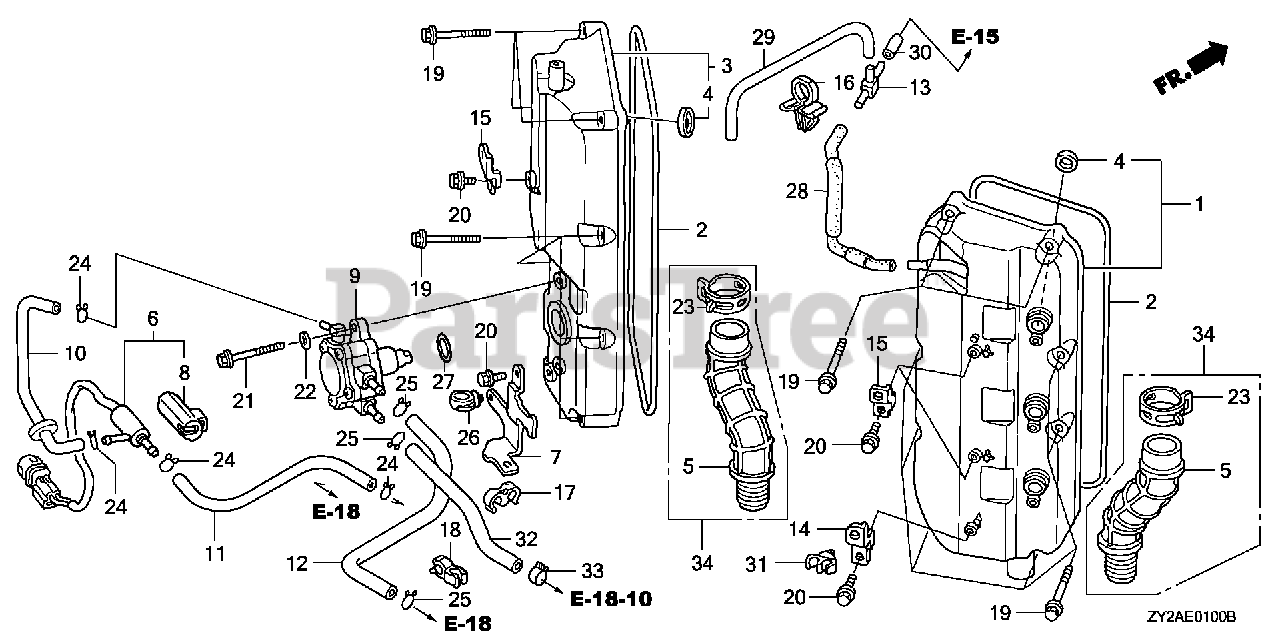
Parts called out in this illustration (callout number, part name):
1	COVER, R. CYLINDER HEAD *NH8* (DARK GRAY)
2	GASKET, HEAD COVER
3	COVER, L. CYLINDER HEAD *NH8* (DARK GRAY)
4	SEAL, SPARK PLUG TUBE (NOK)
5	TUBE, OIL
6	VALVE ASSY., SOLENOID
7	BRACKET, SOLENOID VALVE
8	GROMMET, SOLENOID VALVE
9	PUMP ASSY., FUEL (MSDS)
10	TUBE D, FUEL
11	TUBE E, FUEL
12	TUBE F, FUEL
14	BRACKET, CLIP B
15	BRACKET C, HARNESS CLIP
16	CLIP A, WIRE
17	CLIP, SENSOR HOSE
18	CLIP, SHIFT WIRE
19	BOLT, FLANGE (6X35)
20	BOLT, FLANGE (6X14) (CT200)
21	BOLT, FLANGE (8X32)
22	WASHER, PLAIN (8MM)
23	CLAMP, TUBE (D32.5)
24	CLIP, TUBE (B10)
25	CLIP, TUBE (B12)
26	CLIP, HARNESS
27	O-RING (37X2.4) (ARAI)
28	TUBE A, BREATHER
29	TUBE B, BREATHER
30	TUBE C, BREATHER
31	CLIP D, WASHER TUBE
32	BULK HOSE, FUEL (7.5X8000) (7.3X380)
33	CLAMP, TUBE (D12)
34	TUBE SET, OIL
